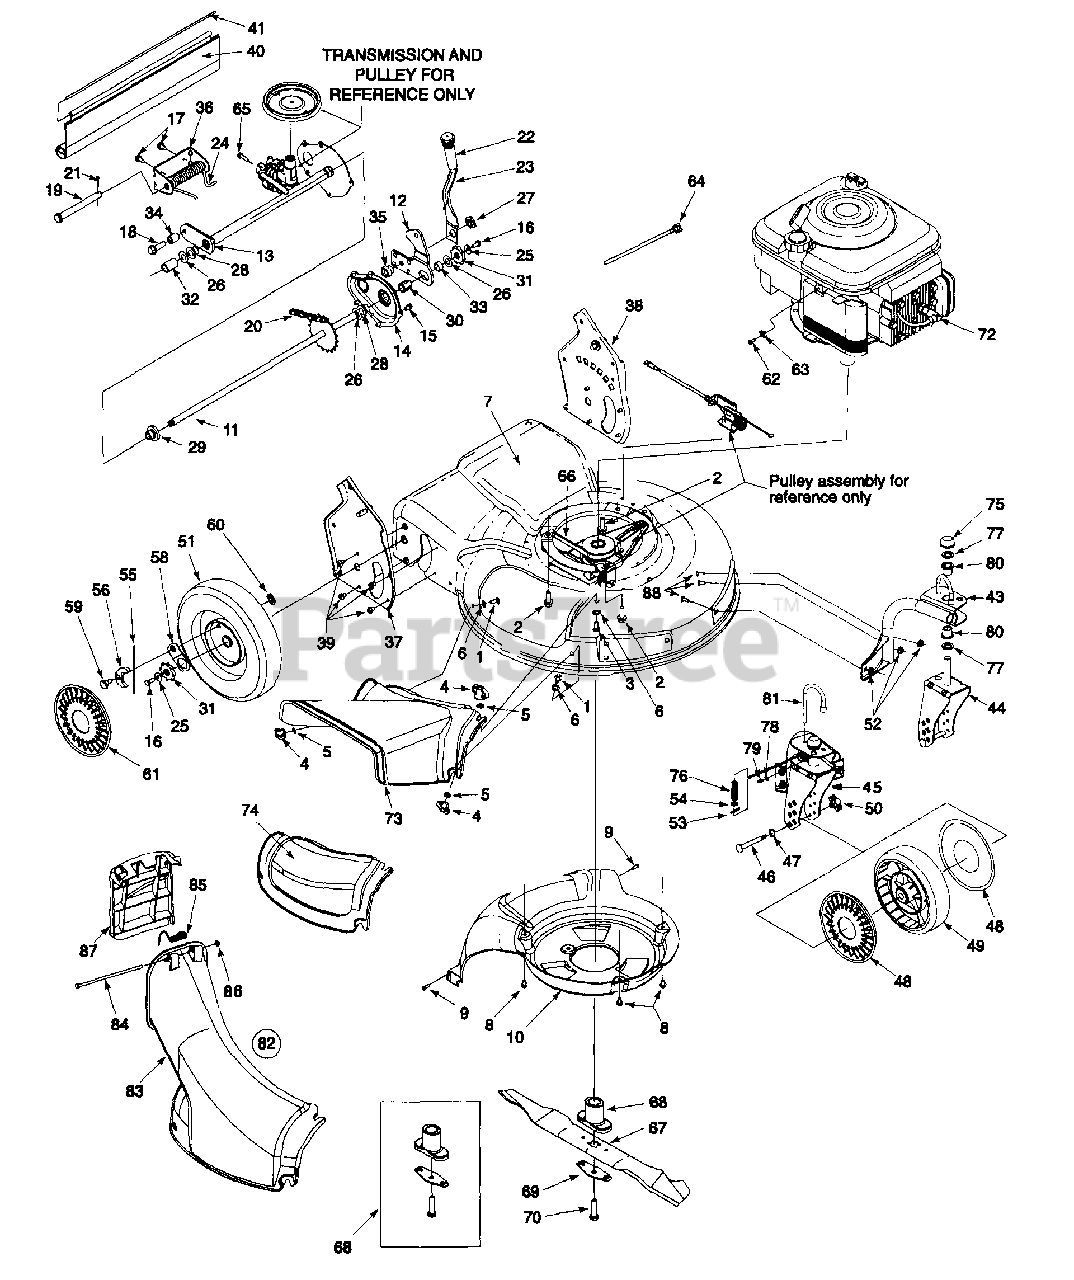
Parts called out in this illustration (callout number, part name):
1	Scr. Carr. 1/4-20 x .62
2	Scr. TT: 3/8-18: 1.00
3	Scr. 1/4-20 x .750
4	Wing Nut 1/4-20
5	Nut, Push .25 I.D. x .50 O.D.
6	Wash. Fl. .334 I.D. x .62 x .03
7	Deck - 21"
8	Scr. TT. 1/4-20 x .375
9	Scr. HL. 1/2-14 x .750
10	Baffle
11	Rear Axle Assembly
12	Pivot Arm Assembly
16	Cap Screw HH 1/4-20 x .620
17	Scr. AB 1/4-14 x .825
18	Scr. 3/8 116 x .25
19	Clevis Pin .50 Dia. x 4.82 Lg.
20	Chain-Endls. #48 .500P x 24 L
21	Cotter Pin .125 O.D. x .75
23	Spring Lever
24	Torsion Spring
25	Bell Wash. .285 x .75 x .082
26	Fl. Wash. .508 I.D. 1.000 x.020
27	Nut Shld. .825 Dia. x .165 Lg.
28	Hx.Flg. Brg. .506 I.D. x .590 L.
29	Hx.Flg. Brg. .506 I.D. x .715 L.
30	Hx. Slv. Brg. .504 I.D. x .830 L.
31	Wheel Rachet
32	Spa. .550 I.D. x .750 O.D.
33	Spa. .51 I.D. x .70 O.D. x 38 L.
34	Spa. .365 x .624 x .700
35	Shld. Spa. .385 I.D. x .715 Lg.
38	Handle Brkt. Ass'y. L.H.
39	Scr. AB 1/4-14 x .500
40	Trail Shield
41	Trail Shield Wire
43	Caster Assembly R.H.
43	Caster Assembly L.H.
44	Caster Bracket Assembly: RH
45	Caster Bracket Assembly: LH
46	Caster Axle .374 Dia x 2.50"
47	Wave Washer
48	Hub Cap, Yellow w/ hole
49	Wheel 7 x 2 Link, Black
50	Wing Nut 1/4-20
51	Wheel 9 x 2 Link Yellow, Slv.
52	Lock Nut 5/15-18
53	Cotter Pin .072 x .12 Lg.
54	Fl. Wash. .330 x .830 x .060
55	Spring, Ratchet, Plastic
56	Pawl - R.H.
56	Pawl - L.H.
58	Ratchet Pawl Plate
59	Scr. Shld. .340 x .285
60	Top Lock Tab Weld Nut 1/4-20
61	Hubcap - Yellow
62	Screw .620 Hx. Slt. Wsh.
63	Casing Clamp, Throttle
64	Cable Tie
65	Hex Scr. 5/16-18
66	Belt
67	21" Mulching Blade
68	Blade Adapter Kit
69	Blade Bell Support
70	Hex Bolt 3/8-24 x 2.5" Lg.
72	Spark Plug Insulator
73	Side Discharge Chute
74	Mulch Cover
75	Push Cap
76	Compression Spring
77	Fl. Wash. .5/8 I.D. x 1" O.D.
78	Fl. Wash. .203 x .403 x .
79	Fitting - Grease
80	Flange Bearing
81	Locking Pin
82	Chute Ass'y
83	Discharge Chute
84	Pivot Rod
85	Torsion Spring
86	Push Cap
87	Chute Door
88	Carr. Bolt 5/16-18 x.62
